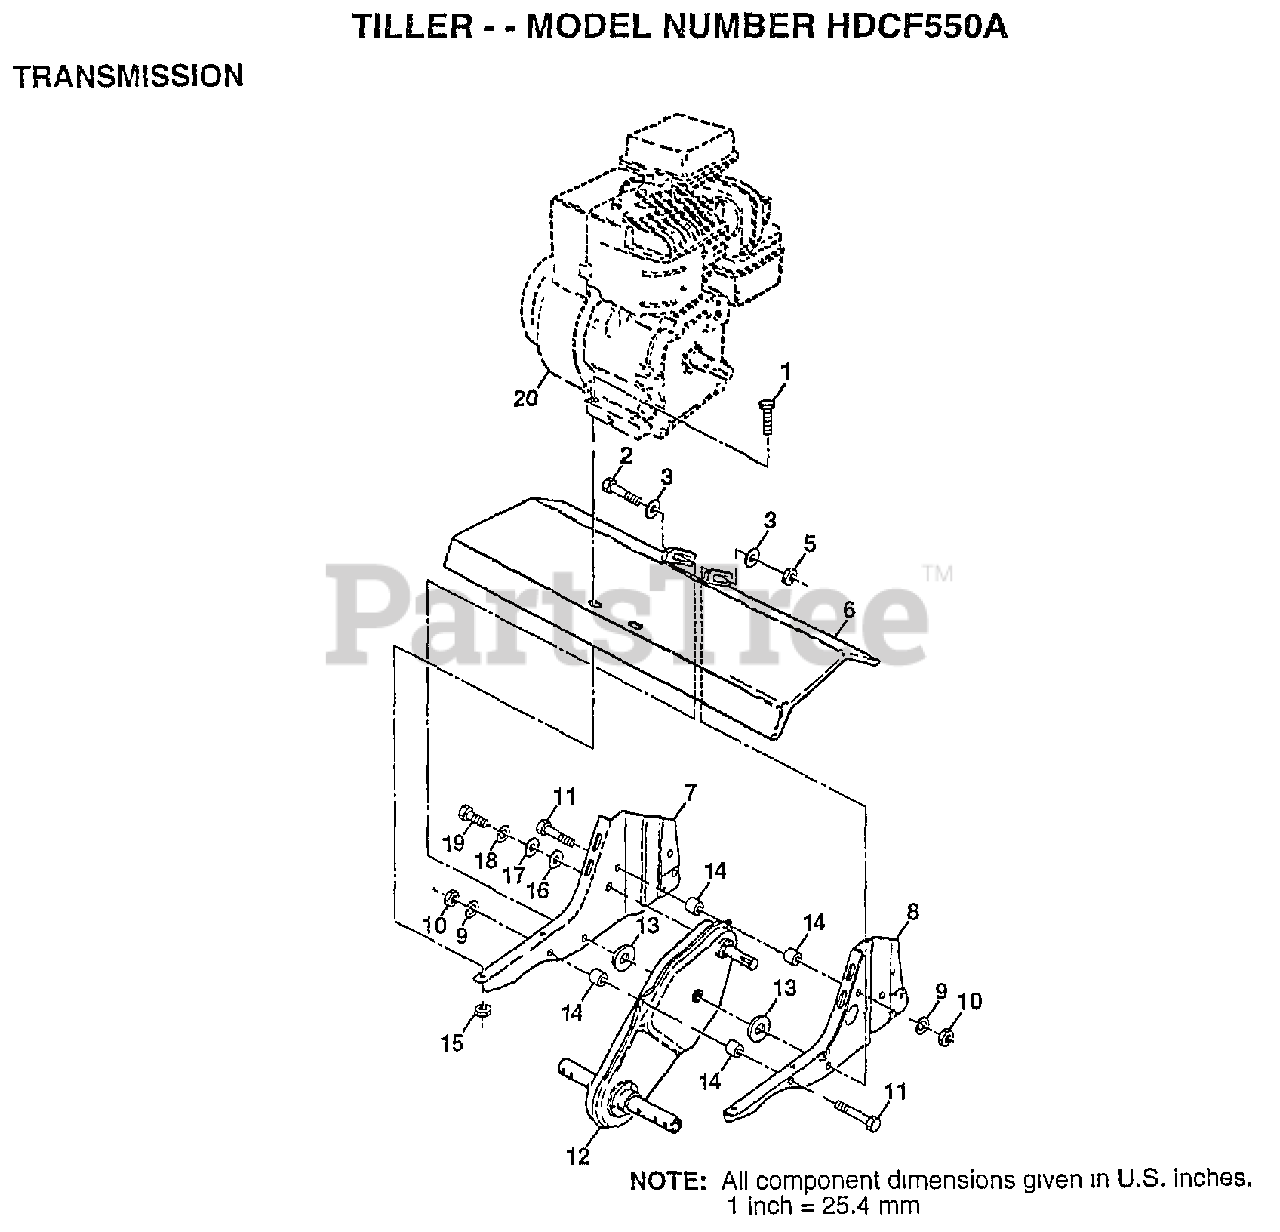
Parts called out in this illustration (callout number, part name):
1	BOLT.HEX.5/16-1.5
2	BOLT HEX 3/8-16
3	WASHER
5	NUT
6	SHIELD TINE
8	BRACKET.ENG.LH.
9	LOCKWASHER
10	NUT.HEX.5/16-18
14	SPLIT SPACER RT
16	WASHER
17	WASHER
18	LOCKWASHER
19	BOLT
